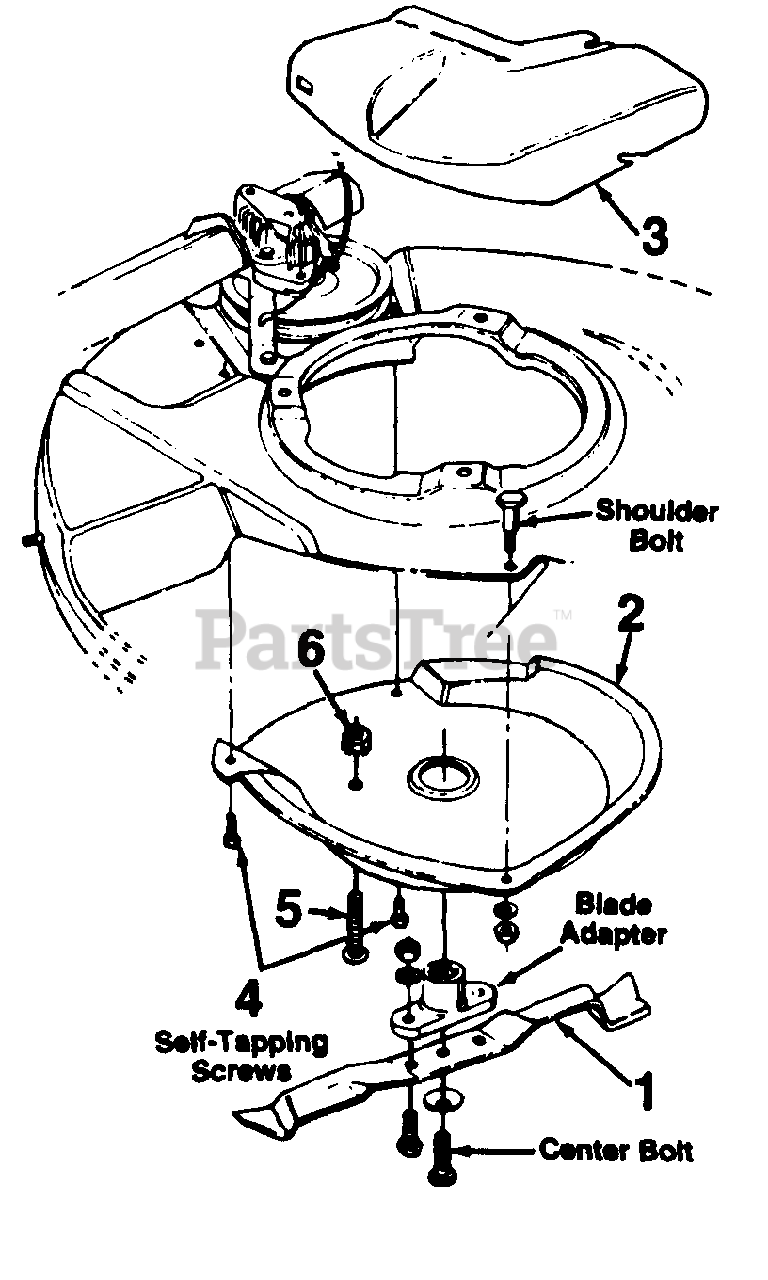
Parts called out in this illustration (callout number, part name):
1	Mulching Blade
4	Self-Tapping Screw
5	Phillips Scr. 1/4-20 x 1.5" Lg.
6	Hex Sems Nut 1/4-20 Thd.
